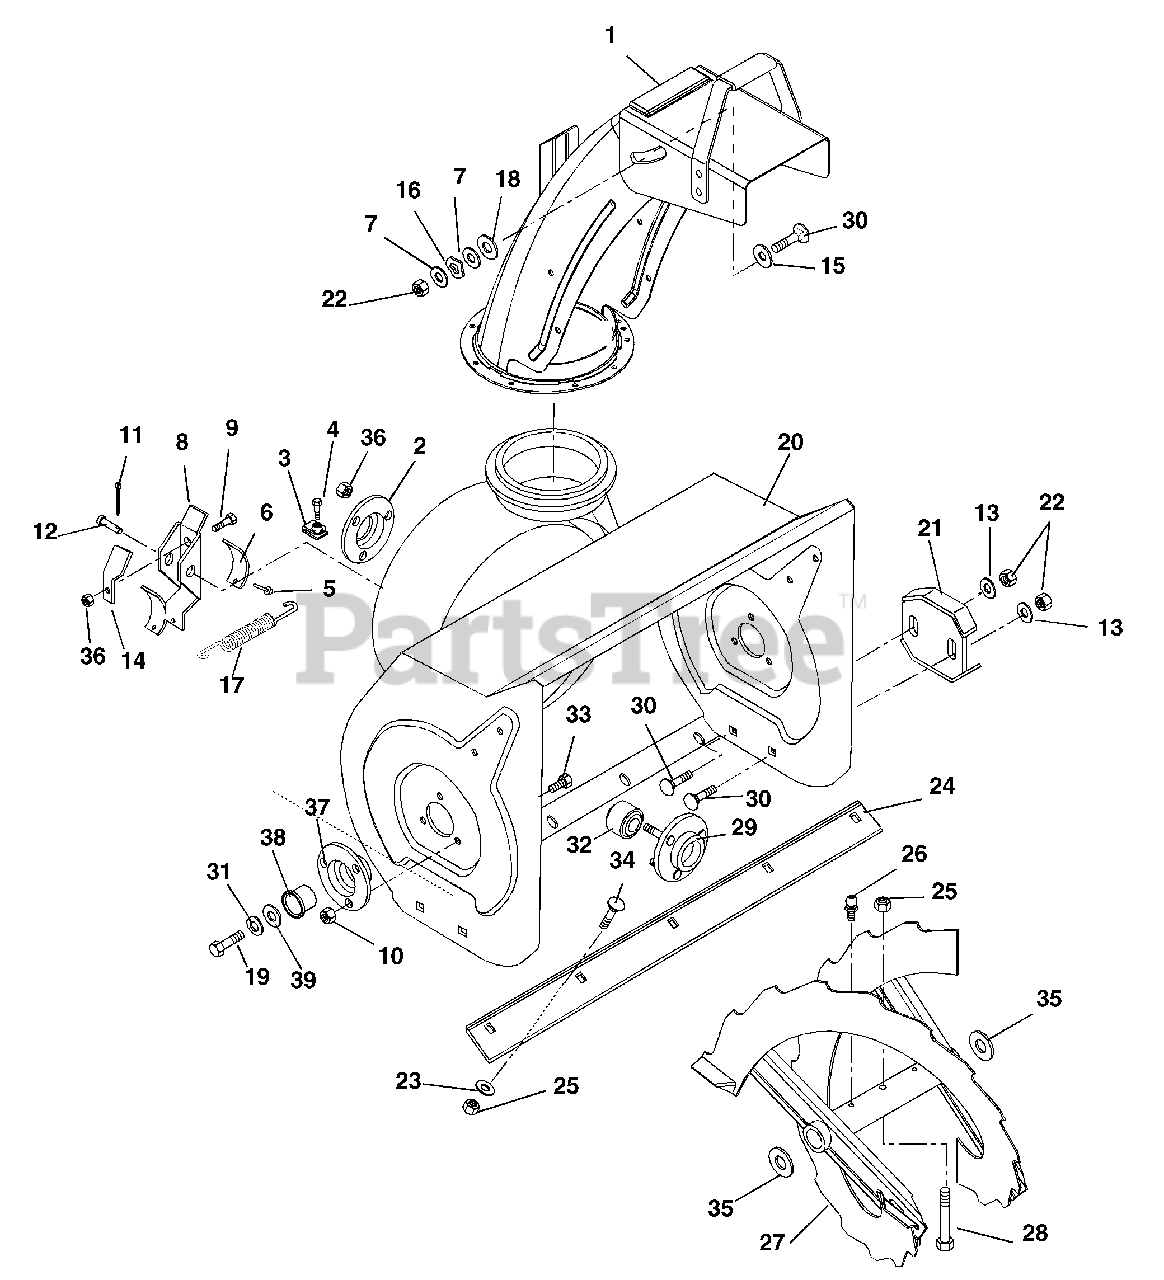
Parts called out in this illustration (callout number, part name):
1	CHUTE, DISCHARGE W/O REMOTE
2	BEARING FLANGE
3	NUT-RETNR .38-16 TINRMAN
4	BLT-SERHFWH .38-16X.75 YWZC
5	RVT-TBLR .187X.437 RH ST PL
6	BRAKE LINING
7	@WSHR-FL-STL.406X.812X.065 YWZ
8	BRAKE ARM ASSEMBLY
9	@BLT-HEX .25-20X.75 GR5 YWZC
10	@NUT-SPNLK-FLG .25-20 YWZC
11	@PIN-CTR .06X.75 EXTPRSQCT YWZ
12	PIN-CLEV .371X1.16 YWZC
13	@WSHR-FL-STL.438X1.00X.083 YWZ
14	ARM EXTENSION
15	WSHR-FL-STL .52X.827X.062 YWZC
16	WAVE WASHER .390X.655X.110
17	SG-TENS .062X.56X8.0 WLD 11
18	WSHR-PLASTIC .390X.875X.062
19	@BLT-HEX .50-13X1.00 GR5 YWZC
20	HOUSING, 24" BLOWER
21	SKID SHOE, REVERSIBLE - ORANGE
22	@NUT-LK-CTR .38-16 YWZC
23	@WSHR-FL-STL.38X.875X.083 YWZC
24	SCRAPER, BLADE 24"
25	@NUT-LK-CTR .31-18 YWZC
26	FTG-LUBE .25-28X.256 YWZC
27	RAKE, RIGHT-24"(1ID X 14.75OD)
28	SHEAR BOLT SERVICE ASSEMBLY
29	BEARING FLANGE
30	BLT-RHHDSQSHNK .38-16X.75 G2YZ
31	WSHR-LK .500X.151 HVY YWZC
32	BRG-BALL .750X1.750X.50
33	BLT-SERNK SL .25-20X.50 YWZC
34	@BLT-RHDSSQNK .31-18X.62 G5YZ
35	WSHR-FL-STL 1.010X1.505X.062YZ
36	@NUT-LK-CTR .25-20 YWZC
37	BEARING SUPPORT
38	BSHG-FLG 1.000X1.12X.62X1.50BR
39	WSHR-FL-STL.511X1.441X.125 YWZ
